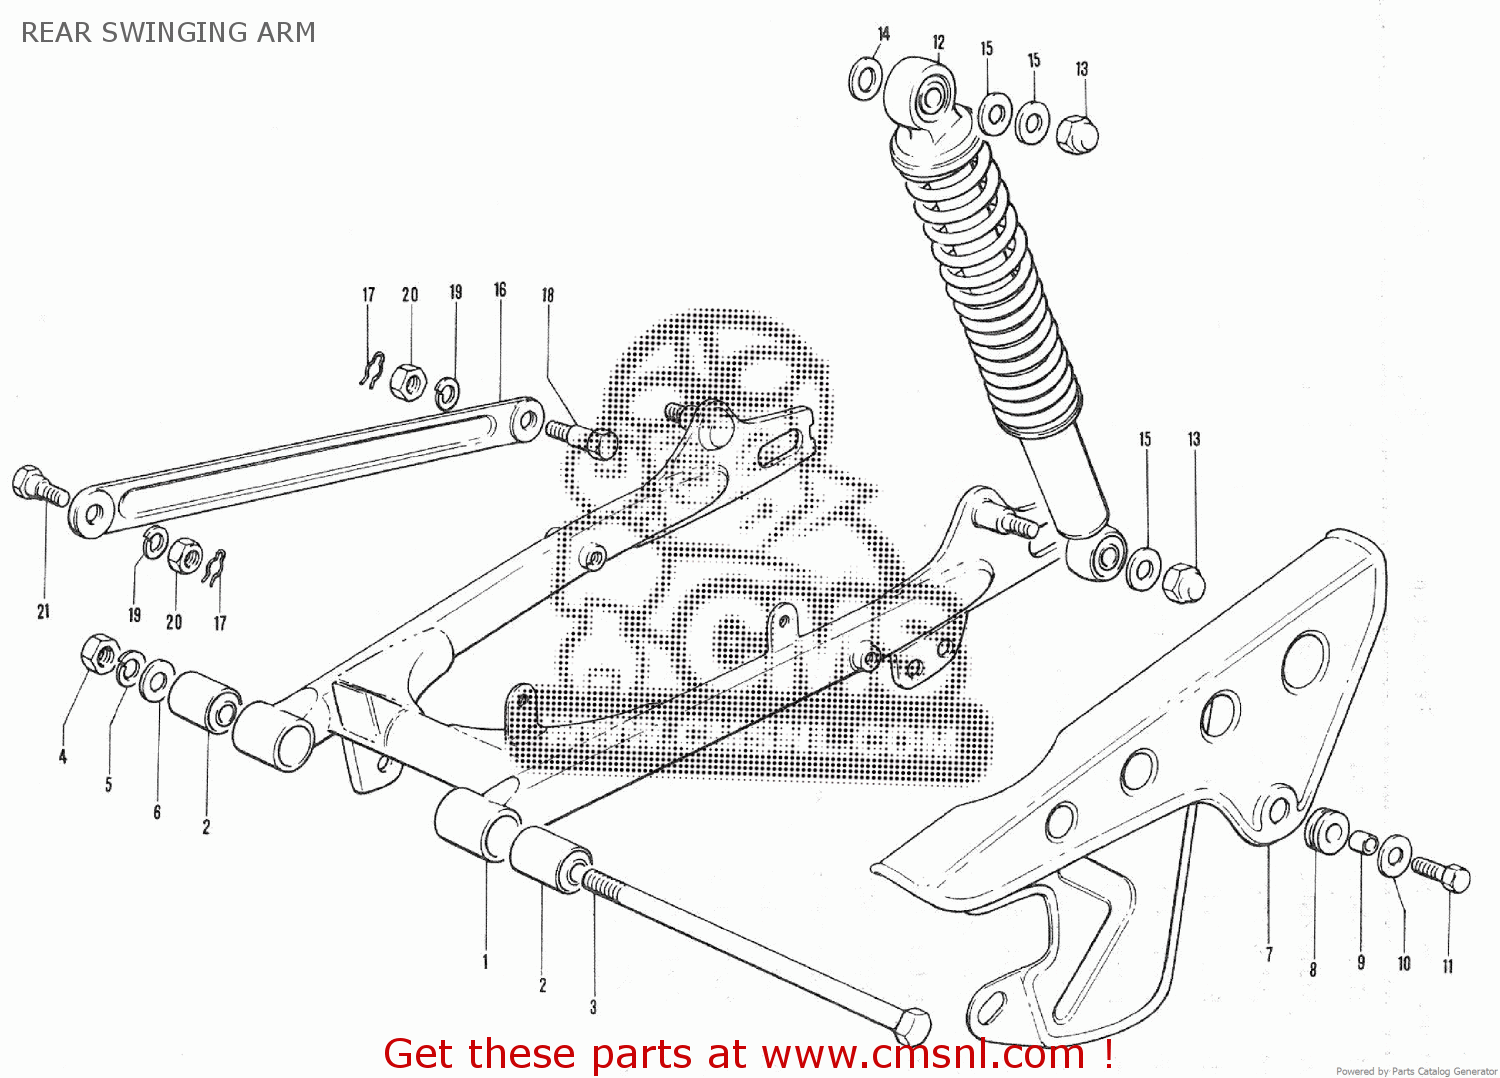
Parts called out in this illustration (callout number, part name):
1	SWING ARM ASSEMBLY,REAR
2	BUSHING(10X23X35)
3	SHAFT,REAR SWING ARM
4	NUT
5	LOCK WASHER
6	WASHER
7	CASE,CHAIN
8	CUSHION
9	SPACER (7X9X7)
10	WASHER (6.5X20X1.2)
11	BOLT
12	ABSORBER ASSEMBLY,REAR SHOCK
13	NUT
14	WASHER
15	WASHER
16	TORQUE LINK,REAR
17	RETAINER,SNAP
18	BOLT,REAR TORGUE LINK,REAR
19	LOCK WASHER
20	NUT
21	BOLT, REAR TORQUE LINK
